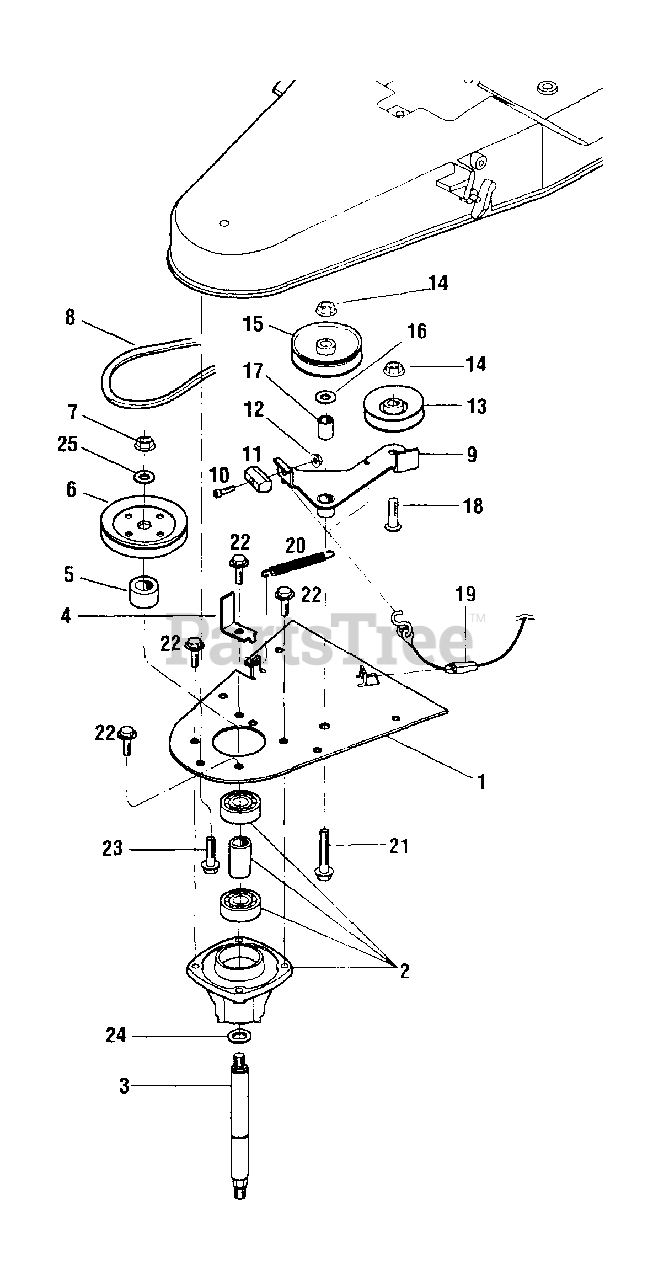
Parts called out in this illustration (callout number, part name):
1	Spindle Mounting Plate
2	Spindle Assembly
3	Spindle Shaft Assembly
4	Belt Guide
5	Spindle Spacer
6	Spindle Pulley
7	Hex Flange Nut, 1/2-13
8	V-Belt
9	Idler Arm/Brake Shoe Assembly
10	Socket Hd Capscrew, 10-24 x 3/4
11	Brake Shoe
12	Hex Lock Nut, 10-24
13	V-Groove Idler Pulley
14	Hex Flange Nut, 3/8-16
15	Flat Idler Pulley
16	Washer, .88 x .382 x .275
17	Idler Arm Spacer
18	Button Head Screw, 3/8-16 x 1-1/2
19	Control Cable
20	Idler Tension Spring
21	Hex Flange Screw, 3/8 x 16 x 2-1/4
22	Hex Flange Screw, 5/16-18 x 3/4
23	Hex Flange Screw, 5/16-18 x 1
24	Hardened Shim, 3/4 ID x 1.022 OD x .060 thick
25	Belleville Washer, 5/8
